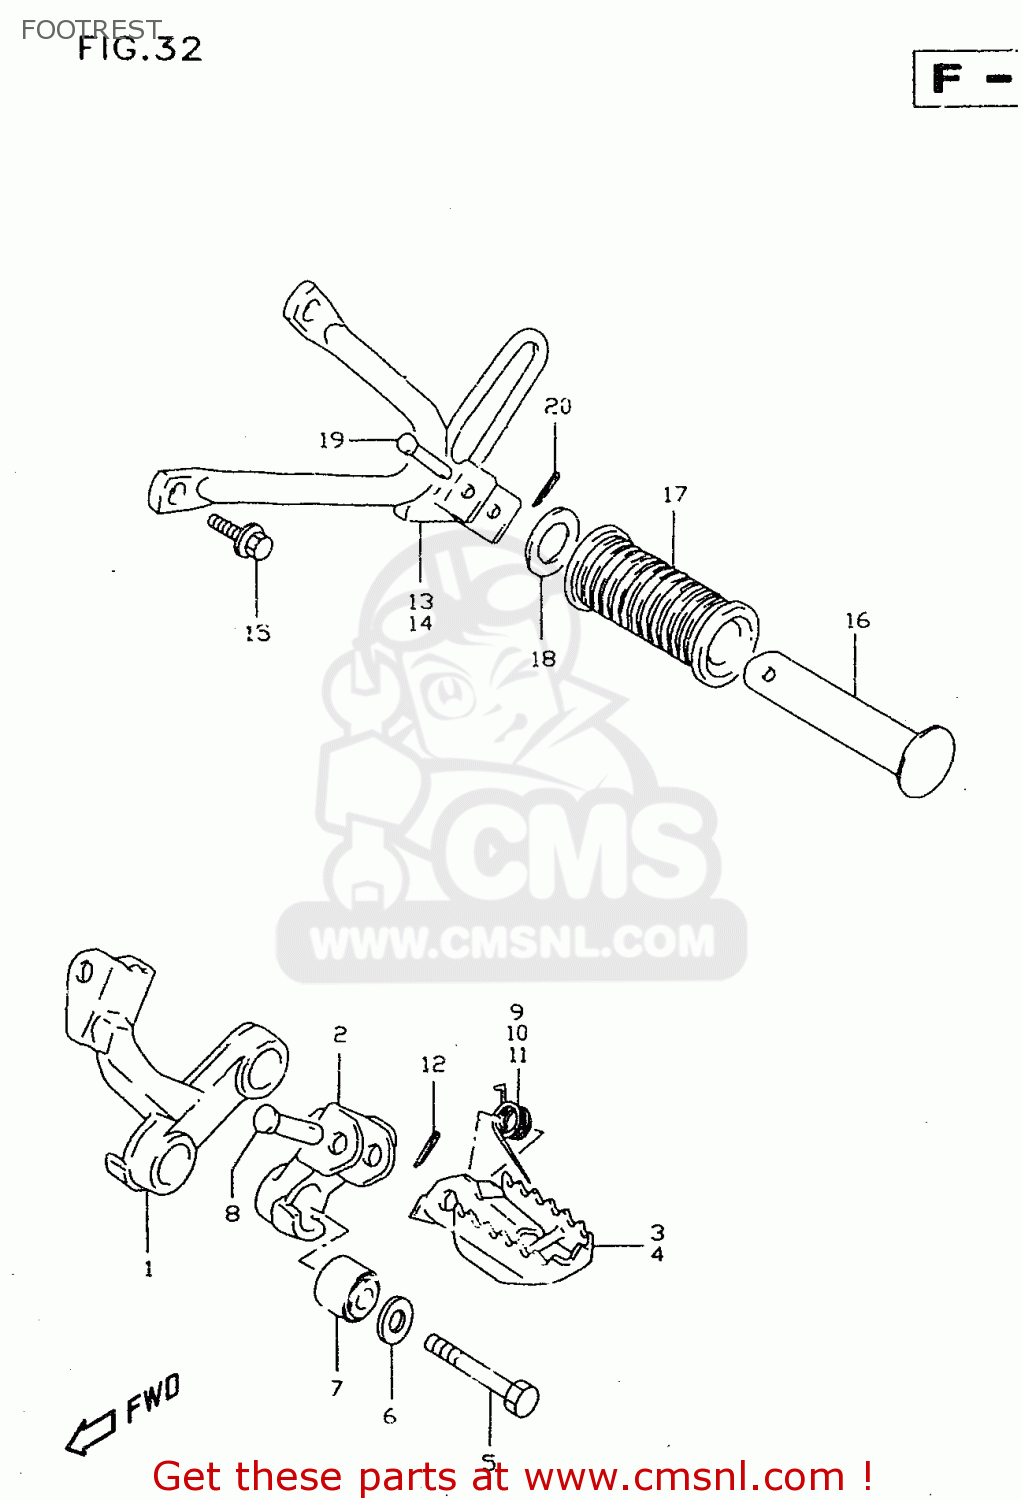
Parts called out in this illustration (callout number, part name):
1	BRACKET,FR FOOTREST,R
2	BRACKET,FR FOOTREST,L
3	FOOTREST COMP,FRONT,RIGHT
4	FOOTREST COMP,FRONT,LEFT
5	BOLT(10X45)
6	WASHER(10.5X22X1.6)
7	BUSH(10.2X25X19)
8	PIN
9	SPRING
10	SPRING
11	SPRING
12	PIN
13	BRACKET,PILLION FOOT,R(BLACK)
14	BRACKET,PILLION FOOT,L(BLACK)
15	BOLT
16	BAR,FOOTREST RUBBER
17	RUBBER,PILLION FOOTREST
18	WASHER(19.5X32X2)
19	PIN
20	PIN
